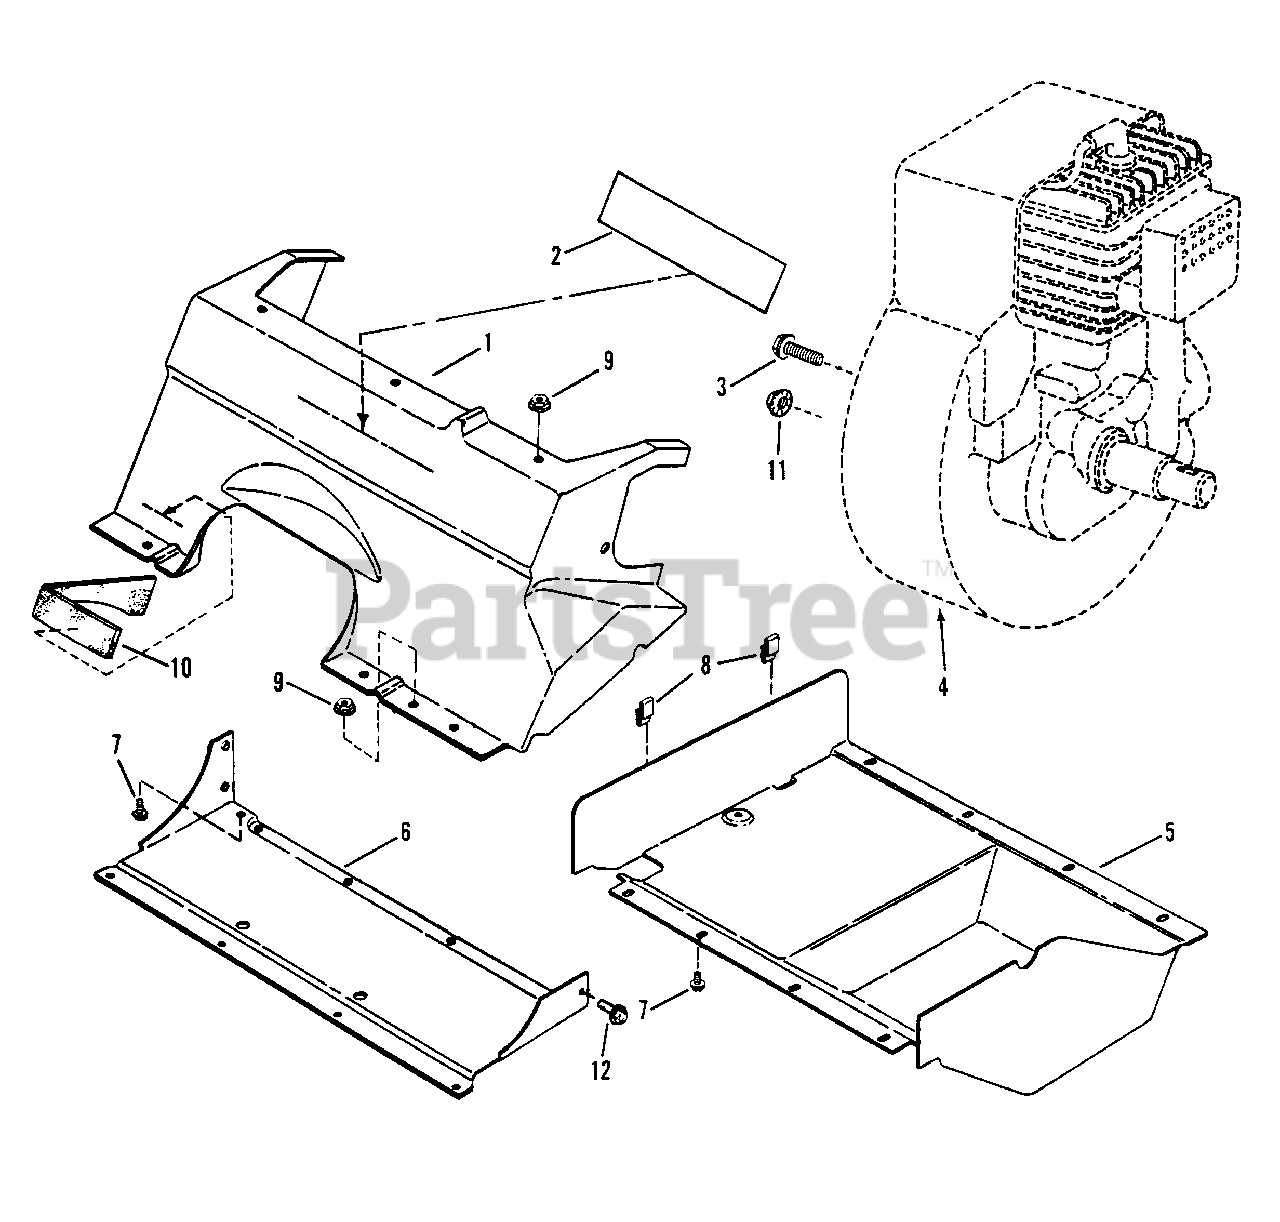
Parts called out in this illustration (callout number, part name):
1	COVER, Top
2	LOGO, BLACKHAWK
3	BOLT, 1/4-20 x 3/8" Hex Flange Lock, Grade 5
4	ENGINE, Tecumseh (2 Cycle)
5	COVER, Bottom
6	BRACE
7	SCREW, #10-32 x 1/4" Self-Tapping
8	CLIP, "S"
9	NUT, #10-24 Hex Flange Lock
10	SEAL, Foam
11	NUT, 5/16-18 Hex Flange Lock, Grade 5
12	SCREW, #10-24 x 1/2" Hex Washer Self-Tap (Torx)
